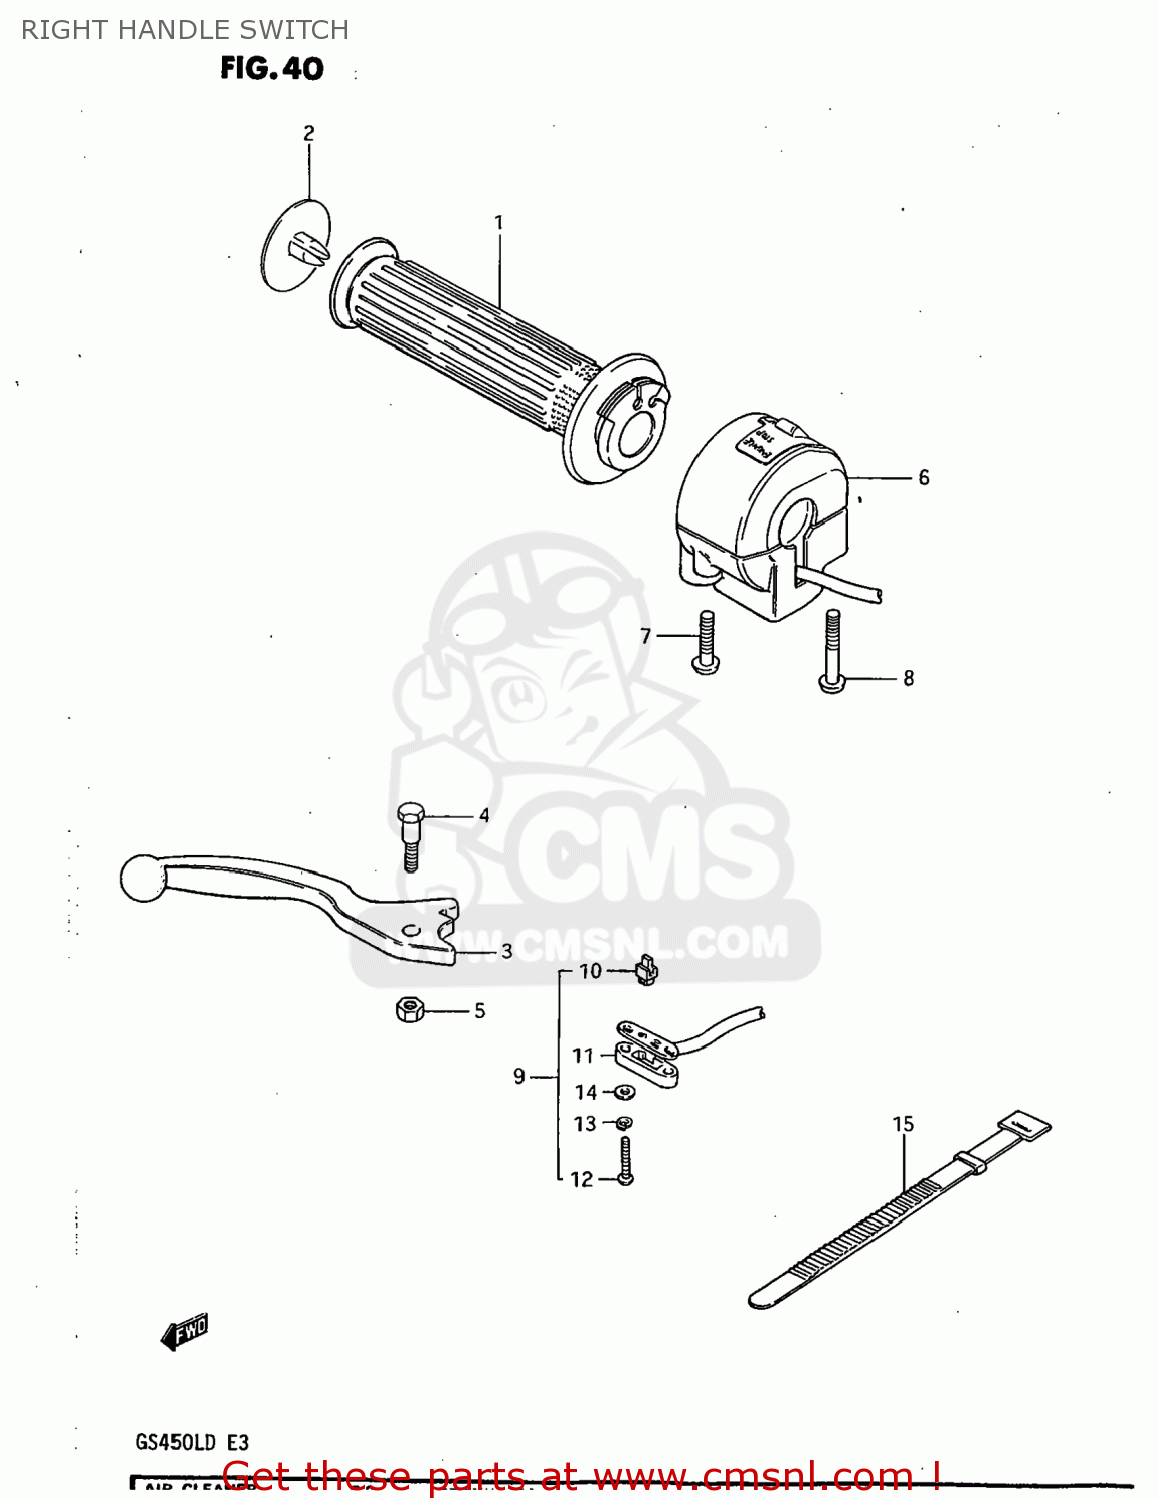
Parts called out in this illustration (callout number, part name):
1	GRIP,THROTTLE
2	CAP,GRIP END
3	LEVER,BRAKE
4	BOLT
5	NUT 6MM
6	SWITCH ASSEMBLY,HANDLE,RIGHT
7	SCREW
8	SCREW
9	SWITCH ASSEMBLY
10	CONTACT,SWITCH
11	COVER,FR BK TERMINAL BASE
12	SCREW
13	LOCK WASHER
14	WASHER
15	CLAMP(L:120)
